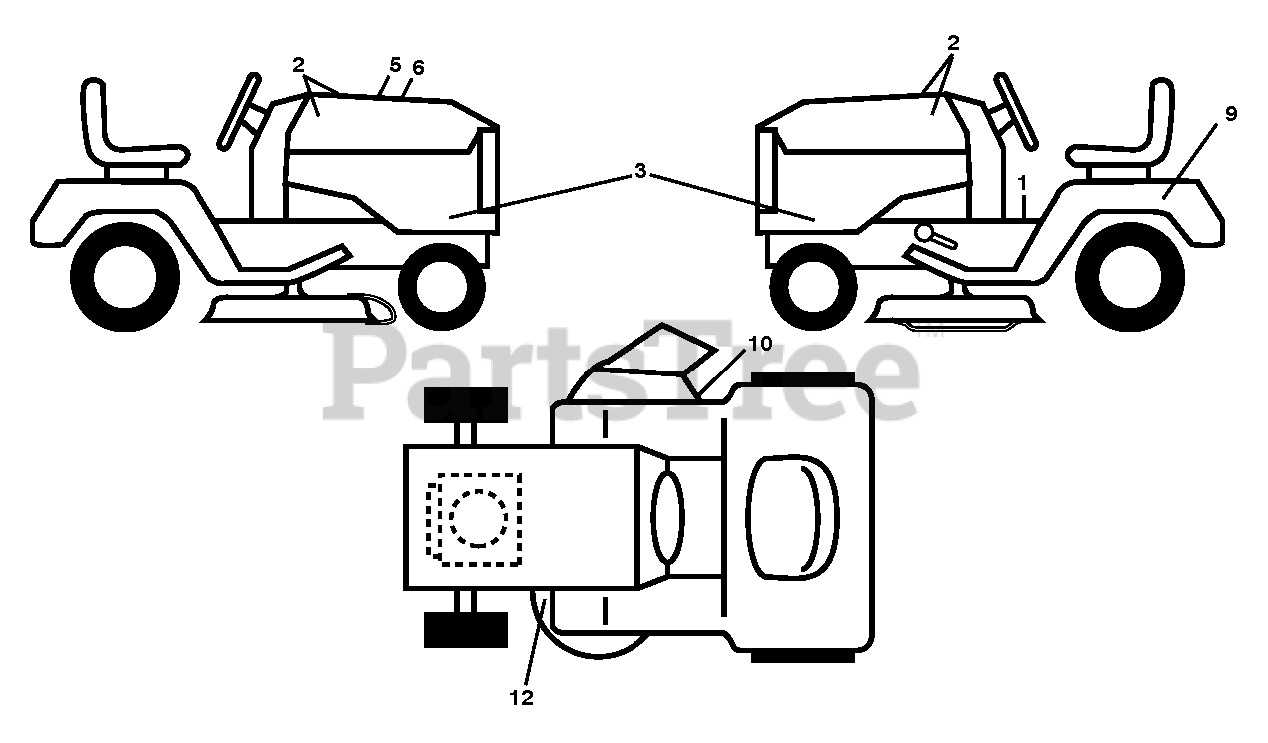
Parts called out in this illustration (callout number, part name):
1	DECAL.FENDER.WARNING
2	DECAL.BADGE.170MM.TEXTLOGO.
3	DECAL.SDPNL.YTH20K46.SET
5	DECAL.WARNING.CUST.RESP.E85.
9	DECAL BTRY SYMBOLS
10	DECAL.WARN.KEEP.HAND.AWAY
12	DECAL V BELT SCHEMATIC
